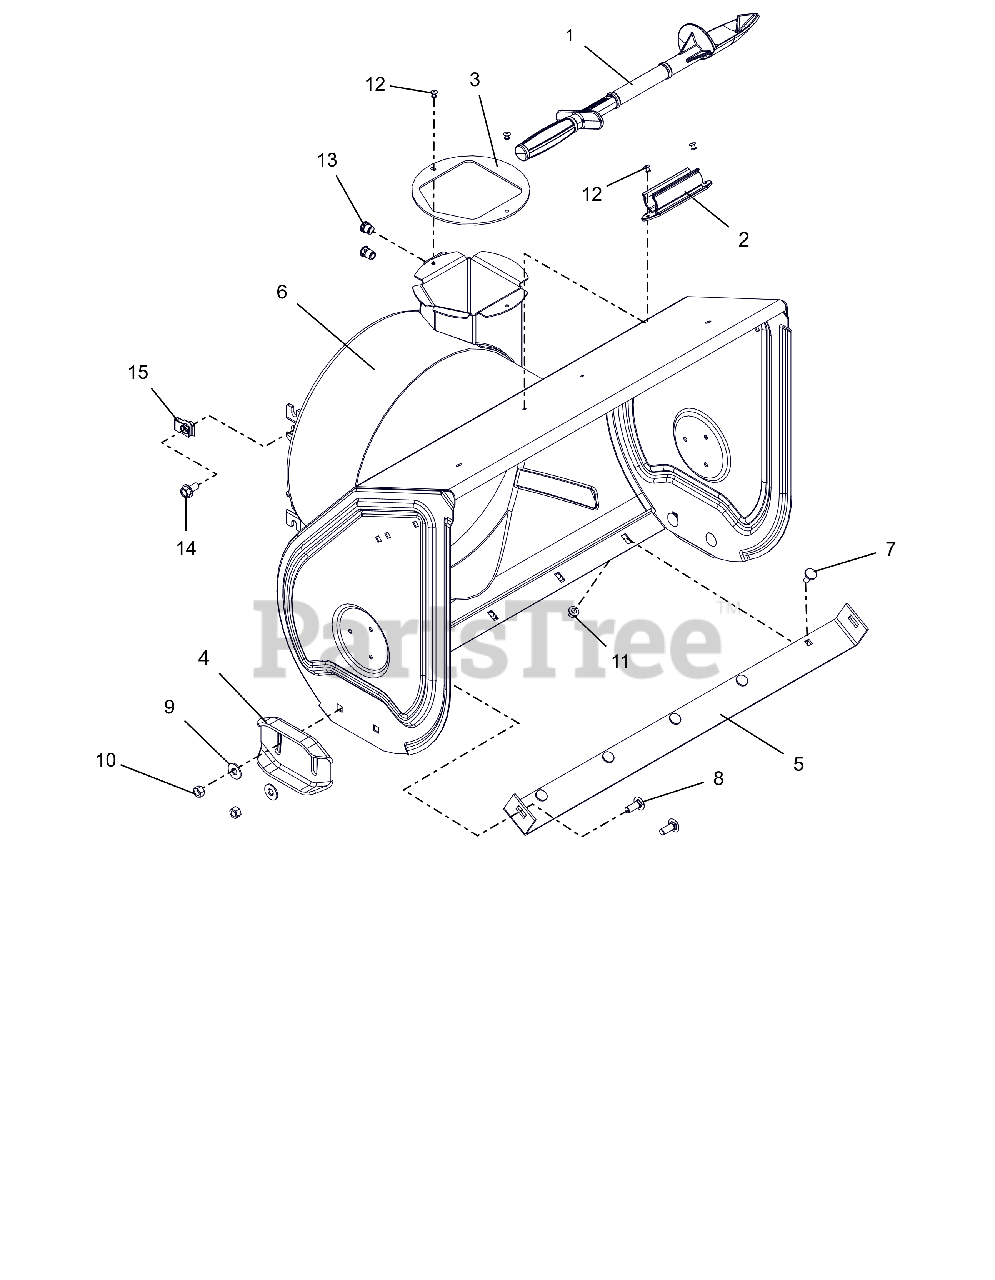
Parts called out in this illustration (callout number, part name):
1	DEVICE, SNOW CLEAN OUT
2	MOUNT, SNOW CLEAN OUT
3	BAFFLE, DISCHARGE NECK
4	SKID SHOE, REVERSIBLE - ORANGE
5	BLADE, SCRAPER - 28"
6	BLOWER HOUSING W/DECAL 28"
7	BOLT, MODIFIED HEAD CARRIAGE
8	BLT,RHSSN .38-16X1.00 G5 ZCC
9	WSHR,FLT .438X1.00X.083 ZCC
10	NUT-LK-CTR .38-16 ZC120
11	NUT-LK-TOP-FLG .312-18 GF ZCC
12	RVT-POP .187 YZ
13	NUT, THREADED INSERT .38-16
14	BLT-SERHFWH .38-16X.75 YWZC
15	NUT-RTNR .375-16X.37
